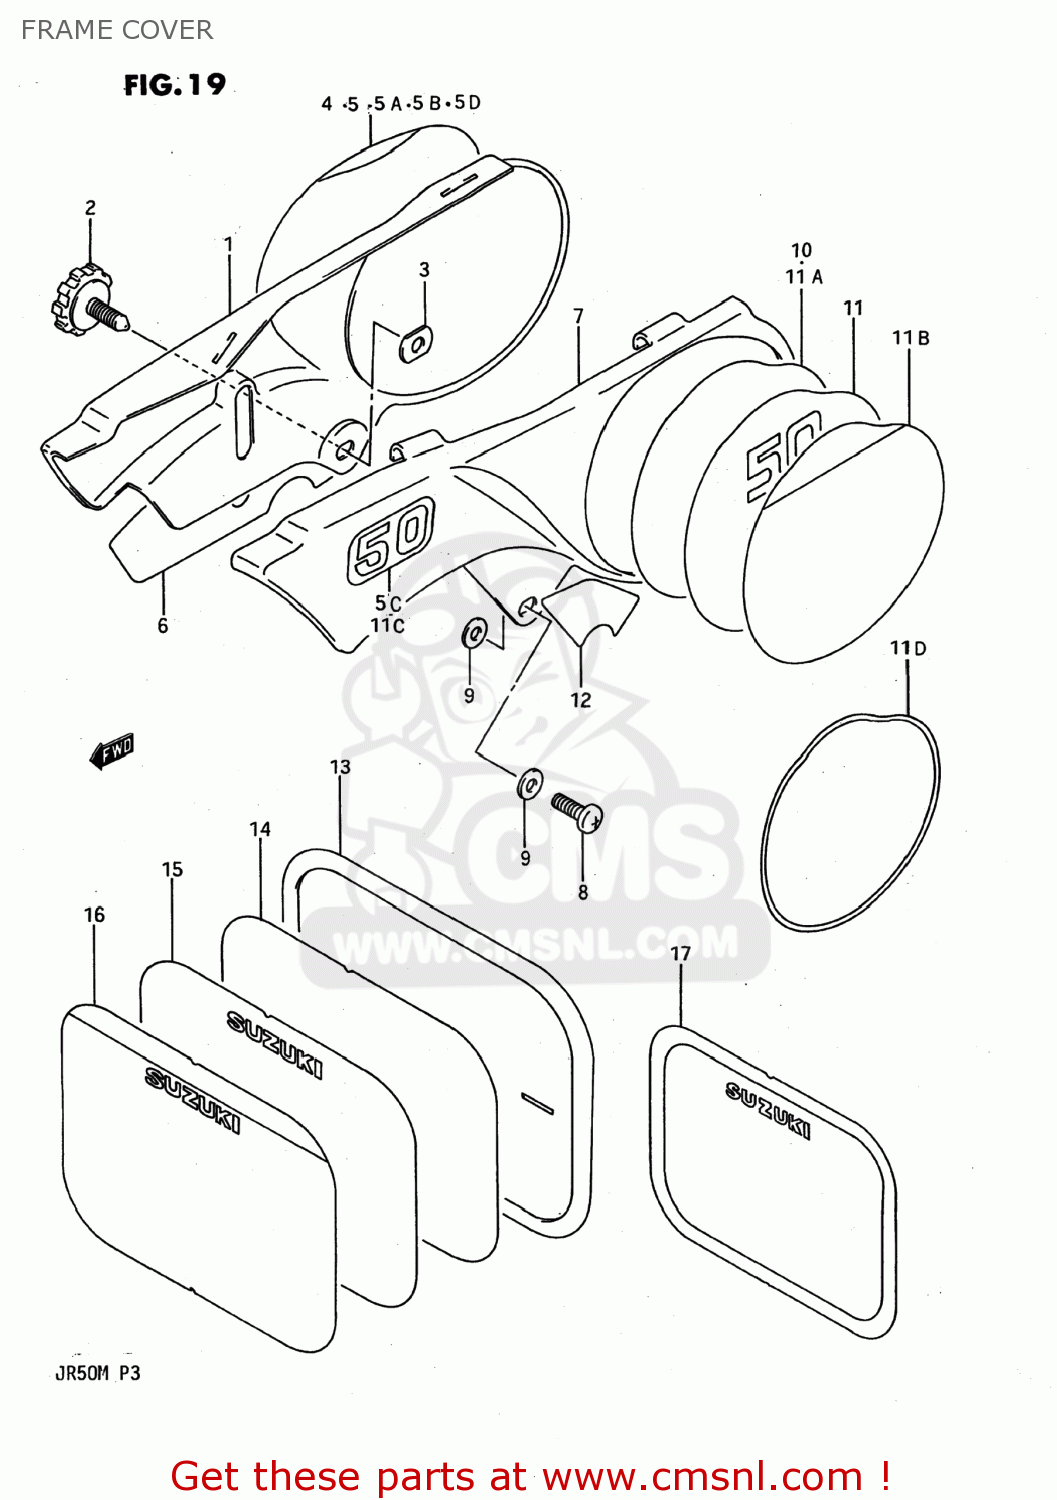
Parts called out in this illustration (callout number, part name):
1	COVER,FRAME,RIGHT
2	KNOB,FRAME COVER,R
3	NUT
4	EMBLEM
5	EMBLEM
5A	EMBLEM
5B	TAPE,FRAME COVER,RIGHT
5C	EMBLEM,FRAME COVER (50)
5D	TAPE,FRAME COVER,RIGHT
6	EMBLEM,FRAME COVER,R LWR
7	COVER,FRAME,LEFT
8	SCREW 6X12
9	WASHER
10	EMBLEM,FRAME COVER
11	EMBLEM,FRAME COVER
11A	EMBLEM,FRAME COVER,LEFT,REAR
11B	TAPE,FRAME COVER,LEFT
11C	EMBLEM,FRAME COVER (50)
11D	TAPE,FRAME COVER,LEFT
12	EMBLEM,FRAME COVER,L LWR
13	PLATE,NUMBER FR
14	EMBLEM,FRONT NUMBER PLATE
15	EMBLEM,FRONT NUMBER PLATE
16	EMBLEM,FRONT NUMBER PLATE
17	EMBLEM,FRONT NUMBER PLATE
